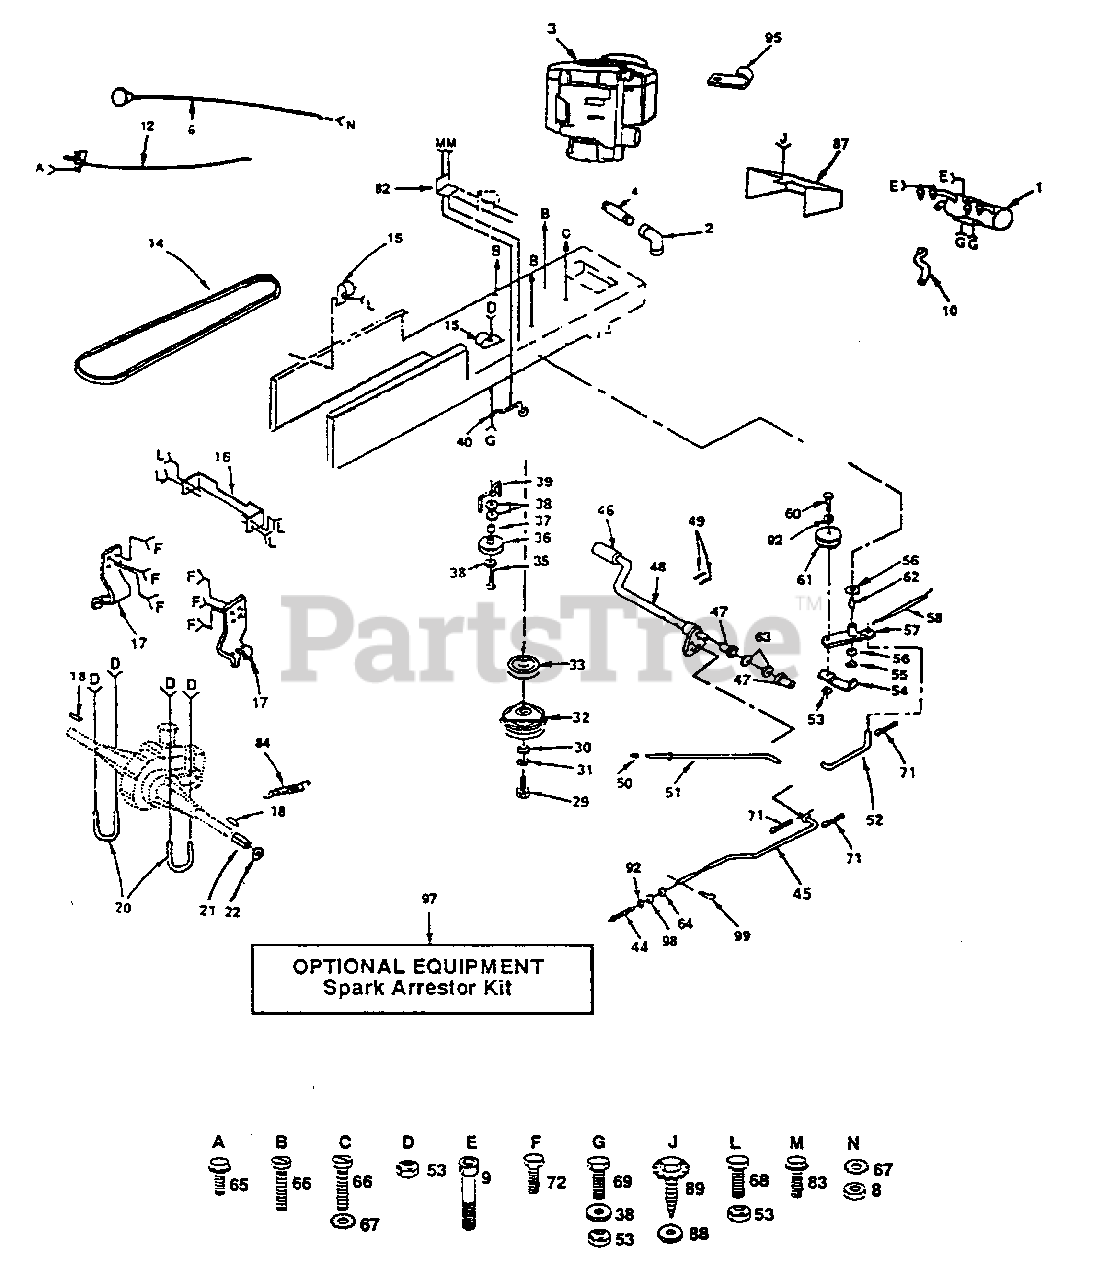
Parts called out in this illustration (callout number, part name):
1	Muffler (AYP part number)
2	Elbow, STD 90 3/8-18NPT (AYP part number)
4	Nipple, Pipe (AYP part number)
6	Control, Choke (AYP part number)
8	Nut, Fin Hex 3/8-24 UNF (AYP part number)
9	Screw, Hex Socket 5/16-18 x 3/4 (AYP part number)
10	Tube Exhaust
12	Control, Throttle (AYP part number)
14	V-Belt, Drive (AYP part number)
15	Clip (AYP part number)
16	Bracket, Mounting, Hydro T/A (AYP part number)
17	Bracket, Transaxle (AYP part number)
18	Key, Square 1/4 x 2 (AYP part number)
20	U-Bolt, 3/8-16 x 2-3/4 (AYP part number)
21	Spacer, Split (AYP part number)
22	Washer 1-1/32 x 1-5/8 x 16 Ga, (AYP part number)
29	Bolt 5/16-18 x 3/4
30	Washer 11/32 x 5/8 x 12 Ga. (AYP part number)
31	Nut, Crownlock 5/16-18
32	Clutch, Electric (AYP part number)
33	Pulley, Engine (AYP part number)
35	Bolt, Hex 3/8-16 x 2-3/4 (AYP part number)
36	Idler, Flat (AYP part number)
37	Spacer (AYP part number)
38	Washer 13/32 x 13/16 x 12 Ga. (AYP part number)
39	Keeper, Belt (AYP part number)
40	Keeper, Belt Engine Lh Lt (AYP part number)
44	Spring, Rod, Brake (AYP part number)
45	Rod, Brake
46	Cover, Pedal (AYP part number)
47	Bearing, Nylon (AYP part number)
48	Shaft, Foot Pedal, Asm. (AYP part number)
49	Pin, Roll 3/16 x 1 (AYP part number)
50	Cap, Plunger (AYP part number)
51	Rod, Brake, Park (AYP part number)
52	Link, Clutch (AYP part number)
53	Locknut, 3/8-16
54	Retainer, Belt (AYP part number)
55	Klip Ring (AYP part number)
56	Washer, Hardened (AYP part number)
57	Arm, Asm, Idler (AYP part number)
58	Spring, Return, Clutch (AYP part number)
60	Bolt, Hex, 3/8-16 x 1-1/2 (AYP part number)
61	Idler, V. Grove
62	Bearing (AYP part number)
63	Washer, 21/32 x 1 x 16 Ga. (AYP part number)
64	Nut (AYP part number)
65	Screw, Hex Thread Cut 1/4-20 x 5/8 (AYP part number)
66	Screw. Thdrol 3/8-16 x 1-1/2 (AYP part number)
67	Washer, Lock Ext Tooth 3/8 (AYP part number)
68	Bolt, Hex 3/8-16 x 3/4 (AYP part number)
69	Bolt, Hex 3/8-16 x 1 (AYP part number)
71	Pin, Cotter, 1/8 x 3/4 (AYP part number)
72	Screw, Hex, Thdrol 3/8-16 X 3/4 (AYP part number)
82	Bracket, Switch (AYP part number)
83	Screw, Tap. Hex Hd. #10-24 x 1/2 Type T (AYP part number)
84	Spring, Brake Return (AYP part number)
87	Shield Heat
88	Washer (AYP part number)
89	Screw Spiderlock Hex Hd #8 x 1/2 (AYP part number)
92	Washer, 13/32 X 13/16 X 16 Ga. (AYP part number)
95	Clamp Muffler (AYP part number)
97	Spark Arrestor (AYP part number)
98	Nut, Hex Jam 3/8 X 16 UNC (AYP part number)
99	Clip, Hairpin (AYP part number)
